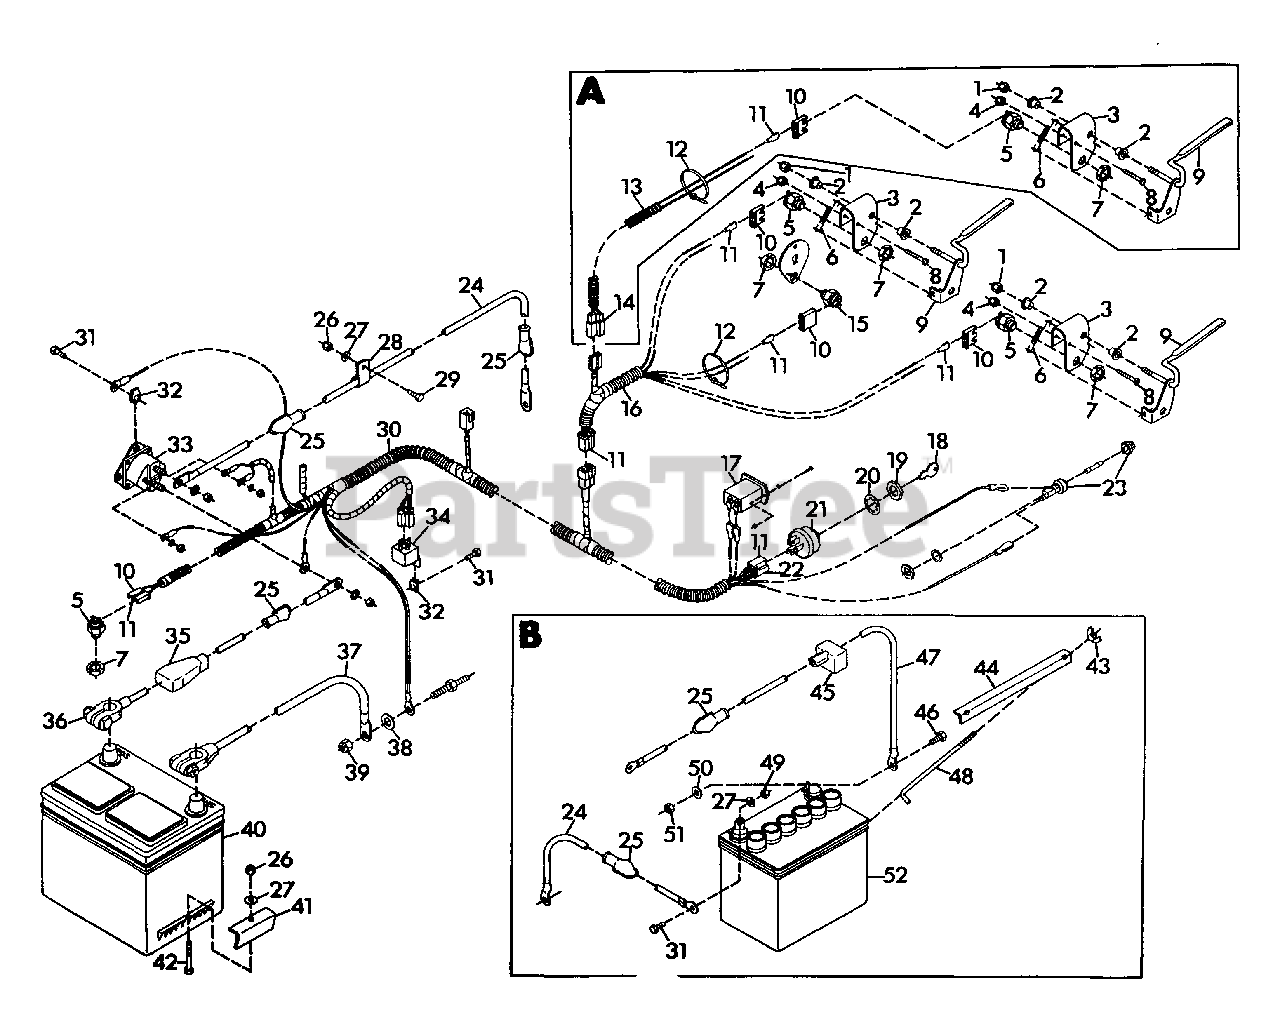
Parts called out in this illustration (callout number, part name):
1	Nut, Lock 5/16-18
2	Bushing, Interlock Lever
3	Bracket, Interlock Mounting
4	Nut, Lock 10-24
5	Switch, interlock
6	Spring, Interlock Lever
7	Nut, Stamped 9/16-18
8	Screw, Machine 10-24 x 1.50 PHD
9	Weldment, Handle
10	Connector, 2-Wire Switch
11	Terminal
12	Tie Wrap, Black
13	Harness, Steering Brake
14	Connector
15	Switch, Neutral Start
16	Harness, Wiring Handlebar
17	Hourmeter
18	Key, Ignition Switch
19	Nut, Jam 9/16-24
20	Washer, Lock
21	Switch, Ignition
22	Connector
23	Fuse, Panel
24	Cable, Switch to Starter (10, 12, and 16 Hp)
24	Cable, Negative Battery (8 Hp)
25	Boot, Battery Cable (10,12 and 16Hp)
25	Boot, Battery Cable (8Hp)
26	Nut, Lock 1/4-20
27	Washer, Flat .281 x .625 x .065
28	Clamp, Nylon
29	Bolt, Hex 1/4-20 x .75
30	Harness, Wiring (10, 12 and 16 Hp)
30	Harness, Wiring (8 Hp)
31	Bolt, Hex 1/4-20 x .625
32	Nut, Speed 1/4-20
33	Switch, Magnetic
34	Relay
35	Cover, Battery Terminal
36	Cable, Positive Battery
37	Cable, Negative Battery (10, 12, and 16 Hp)
38	Washer, Flat .469 x .938 x .065
39	Nut, Lock 3/8-16
40	Battery, 12 Volt (10, 12 and 16 Hp)
41	Clamp
42	Bolt, Hex 1/4-20 x 2.00
43	Nut, Wing 1/4-20
44	Hold Down, Battery
45	Boot, Battery Cable
46	Bolt, Hex 5/16-18 x .625
47	Cable, Battery To Solenoid (8 Hp)
48	Hook, Battery Hold Down
49	Nut, Hex 1/4-20
50	Washer, Flat .344 x .688 x .065
51	Nut, Hex 5/16-18
52	Battery, 12 Volt (8 Hp)
